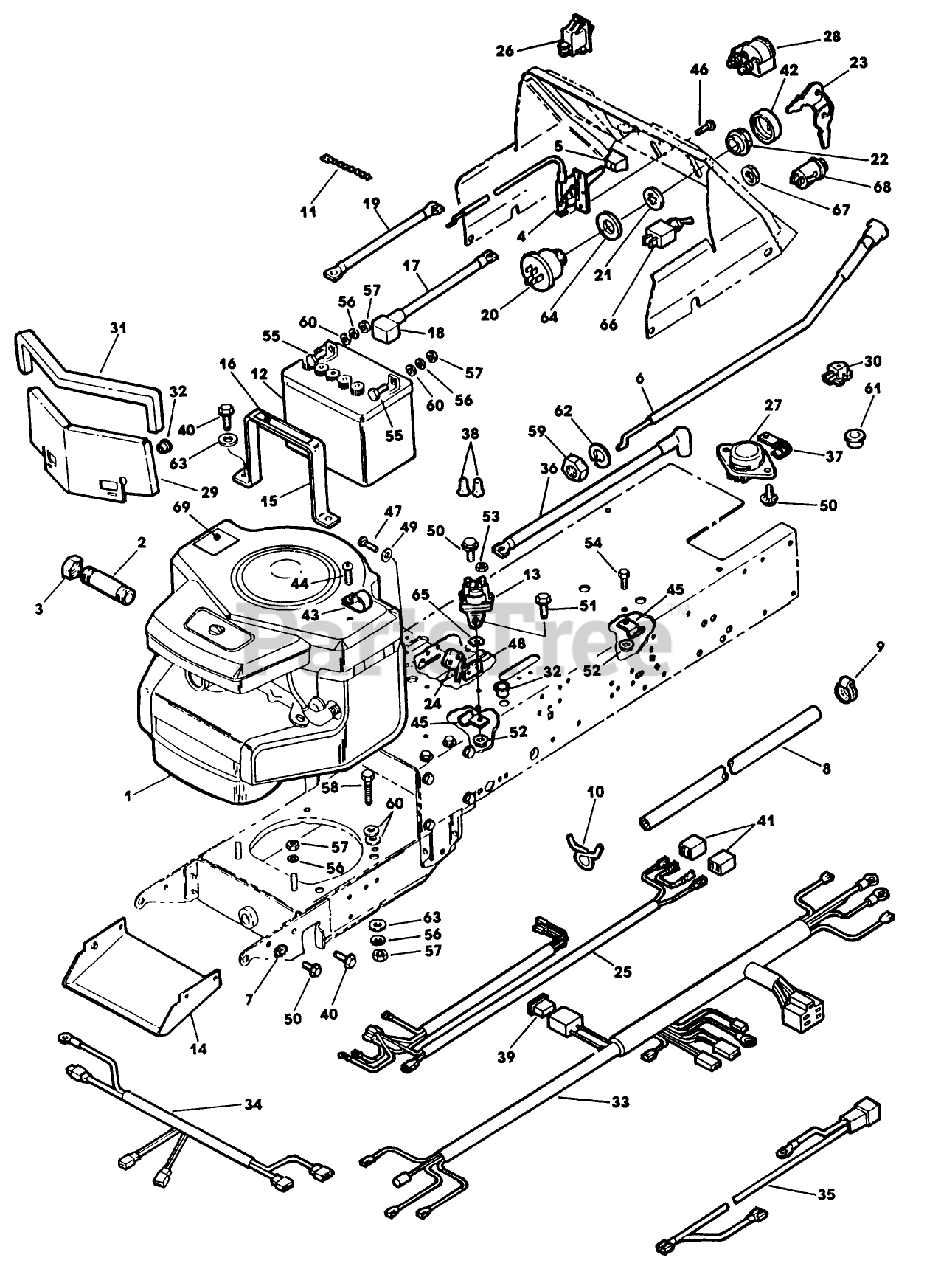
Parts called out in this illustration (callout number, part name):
4	THROTTLE CONTROL
5	THROTTLE KNOB
10	CLAMP
13	SOLENOID
22	NUT
23	KEY
24	SWITCH
26	SWITCH ASSEMBLY
27	SWITCH,SEAT
30	SWITCH
31	FOAM STRIP
33	WIRE HARNESS
42	BEZEL
53	NUT-HEX
54	SCREW-HH
55	SCREW - HEX
57	NUT SS
59	NUT-HEX
62	WASHER
64	WASHER
66	SWITCH-PTO W/SAFTY
68	LIGHT-PTO INDICTOR
